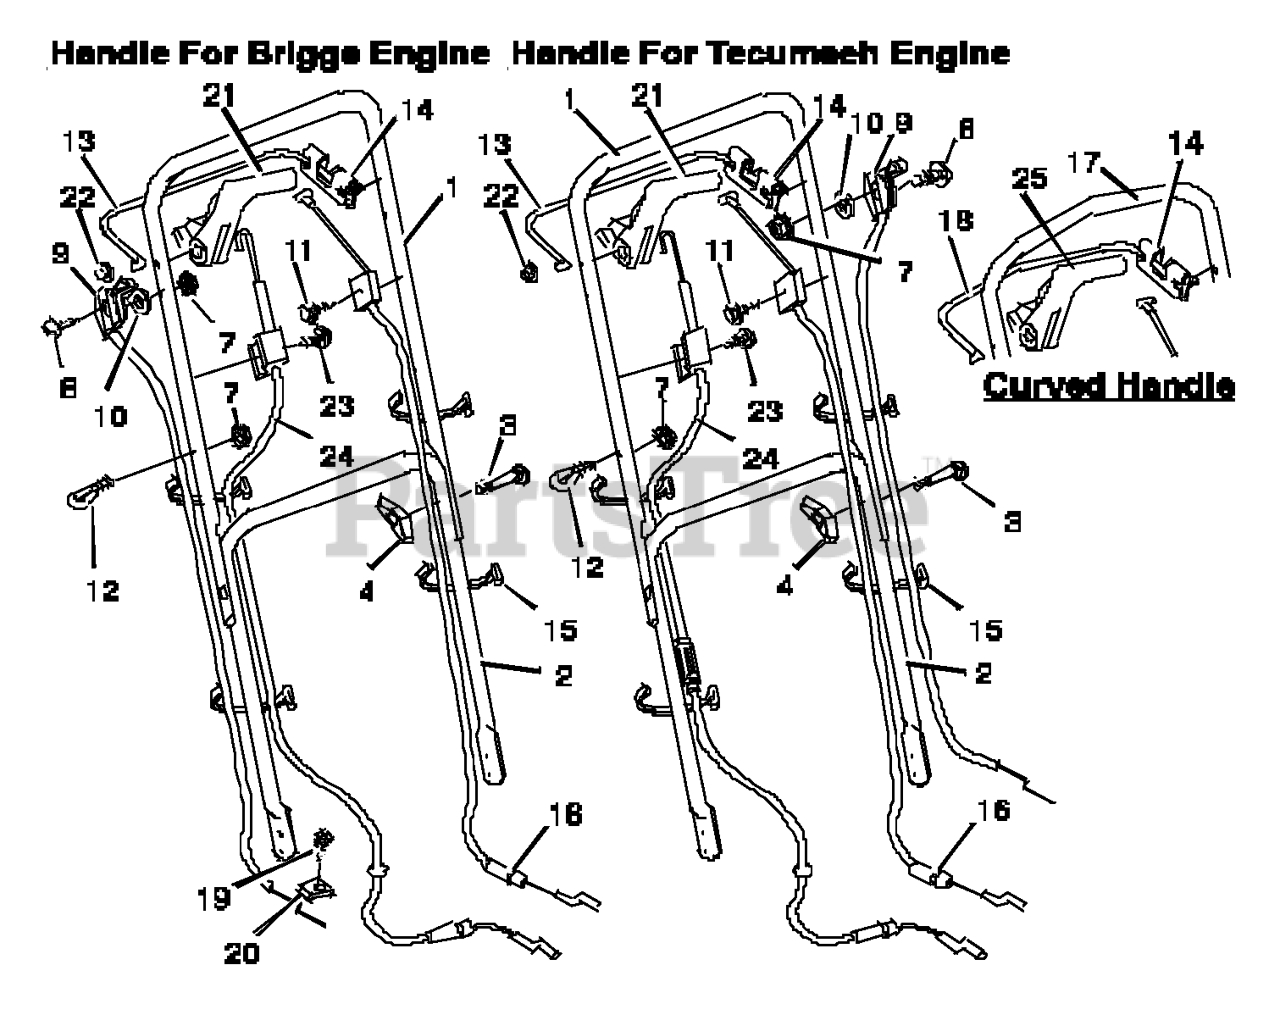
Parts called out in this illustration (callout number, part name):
1	Handle, Upper - Straight (Black)
2	Handle, Lower (Black)
4	Knob, Plastic
7	Locknut
9	Throttle Control
12	GUIDE, ROPE
13	Stop Lever - Straight
14	Bracket, Stop Lever
15	Fastener, Cable
16	Engine Stop Cable *
17	Handle, Upper - Curved (Black)
18	Stop Lever - Curved
19	Screw *
20	Clamp
21	Lever, Drive - Straight
22	Push On Cap
24	Cable, Drive
25	Lever, Drive - Curved
